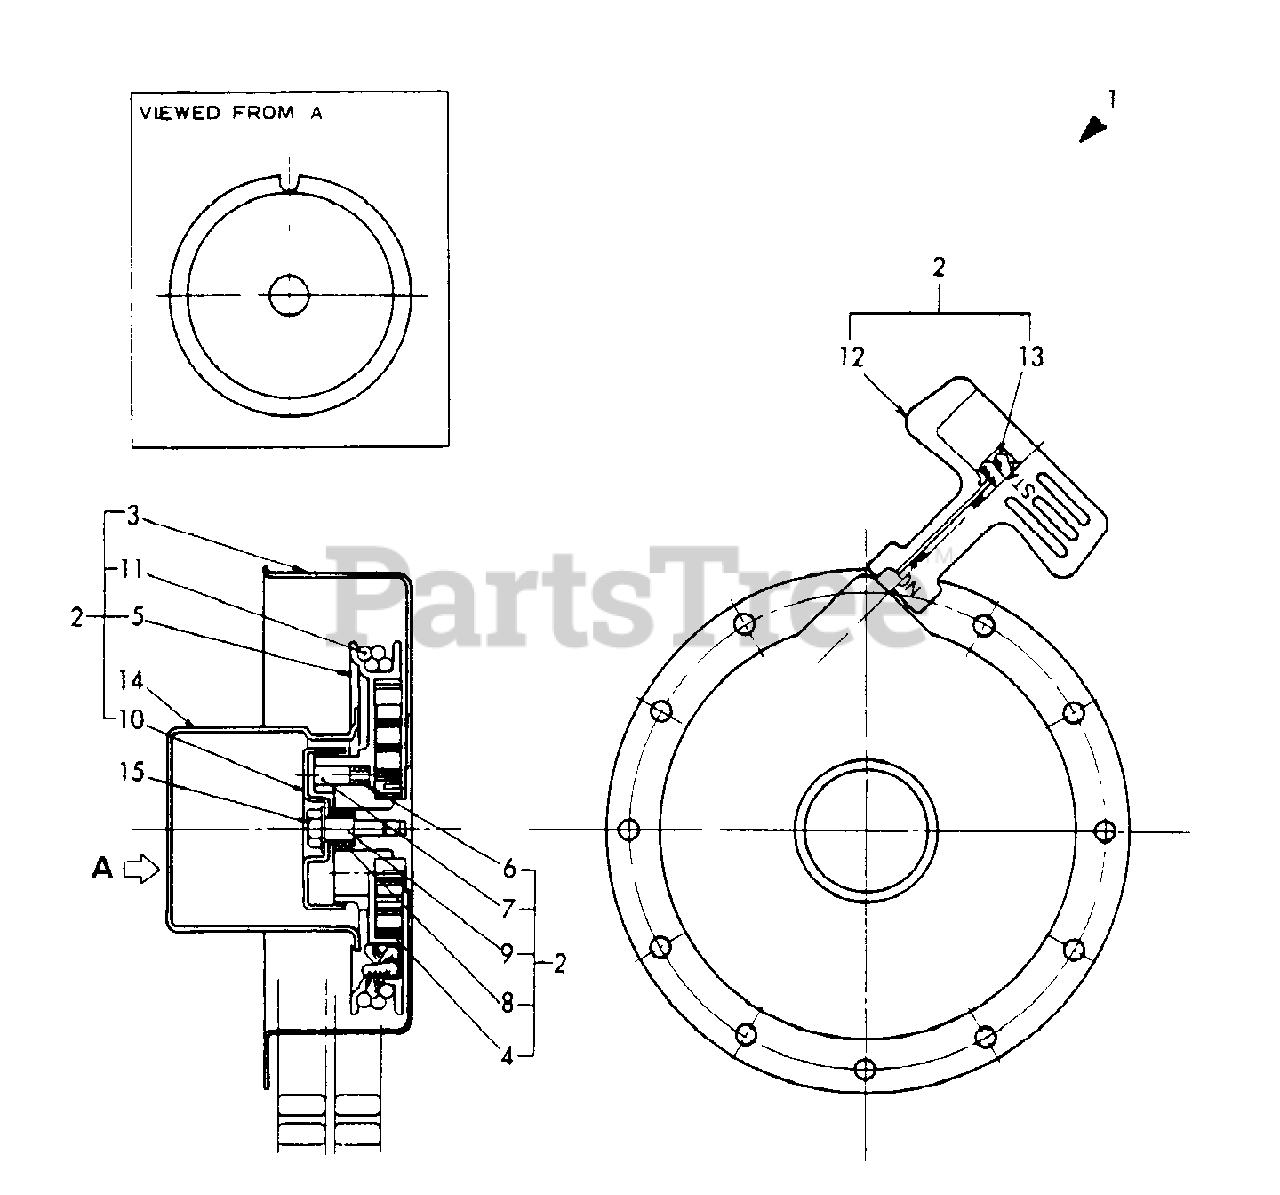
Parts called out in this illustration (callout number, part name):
1	STARTER ASSY
2	STARTER ASSY
3	CASE, STARTER
4	SPRING
5	REEL, ROPE
6	SPRING
7	PAWL, STARTER
8	SPRING
9	SCREW, CENTER
10	RETAINER
11	ROPE, STARTER
12	GRIP, STARTER
13	RETAINER
14	PULLEY, STARTER
15	BOLT - 6X12 -- PLATED
